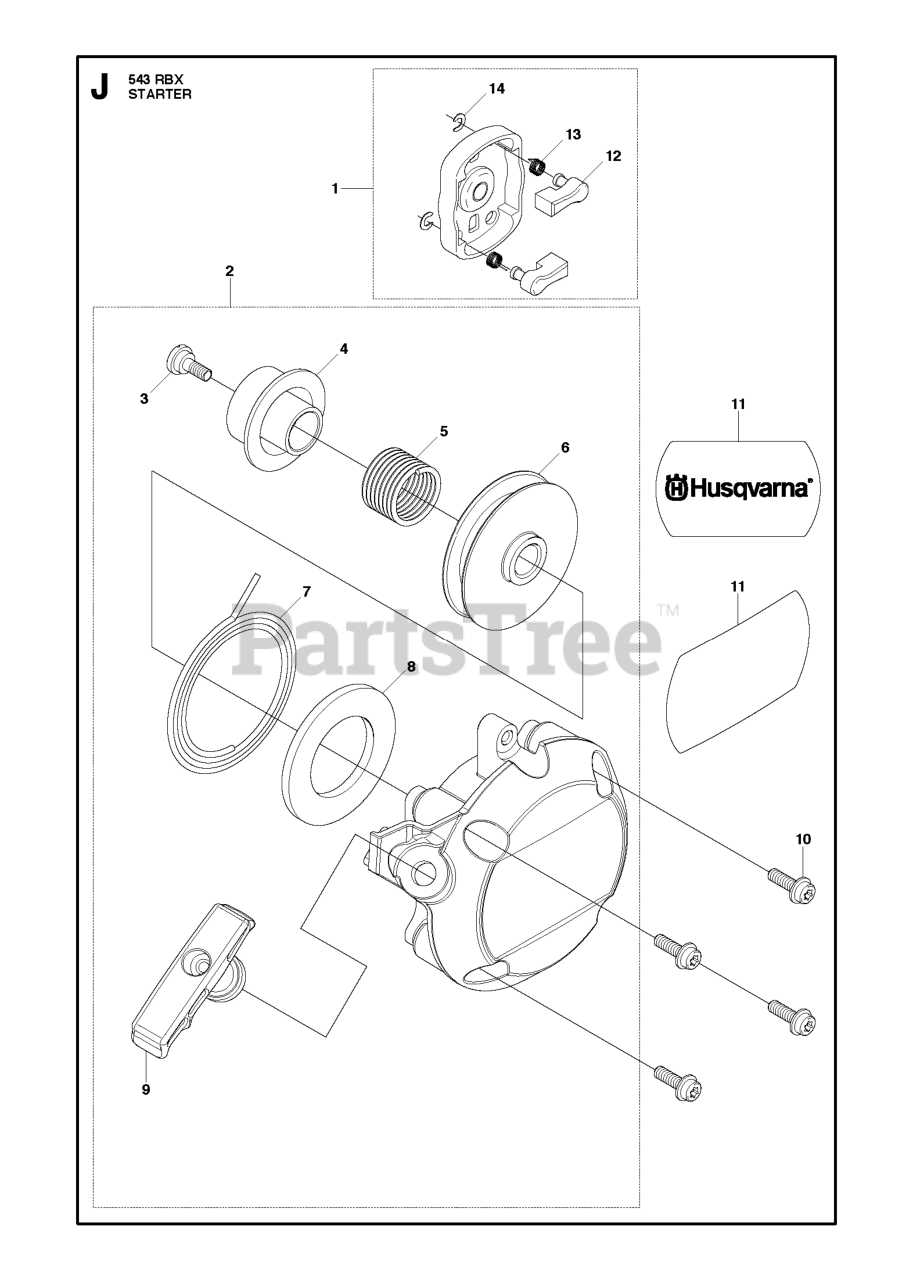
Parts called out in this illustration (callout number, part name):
1	PULLEY ASSY
4	PLATE, CAM
5	SPRING, DAMPER
8	SPRING,SPIRAL
